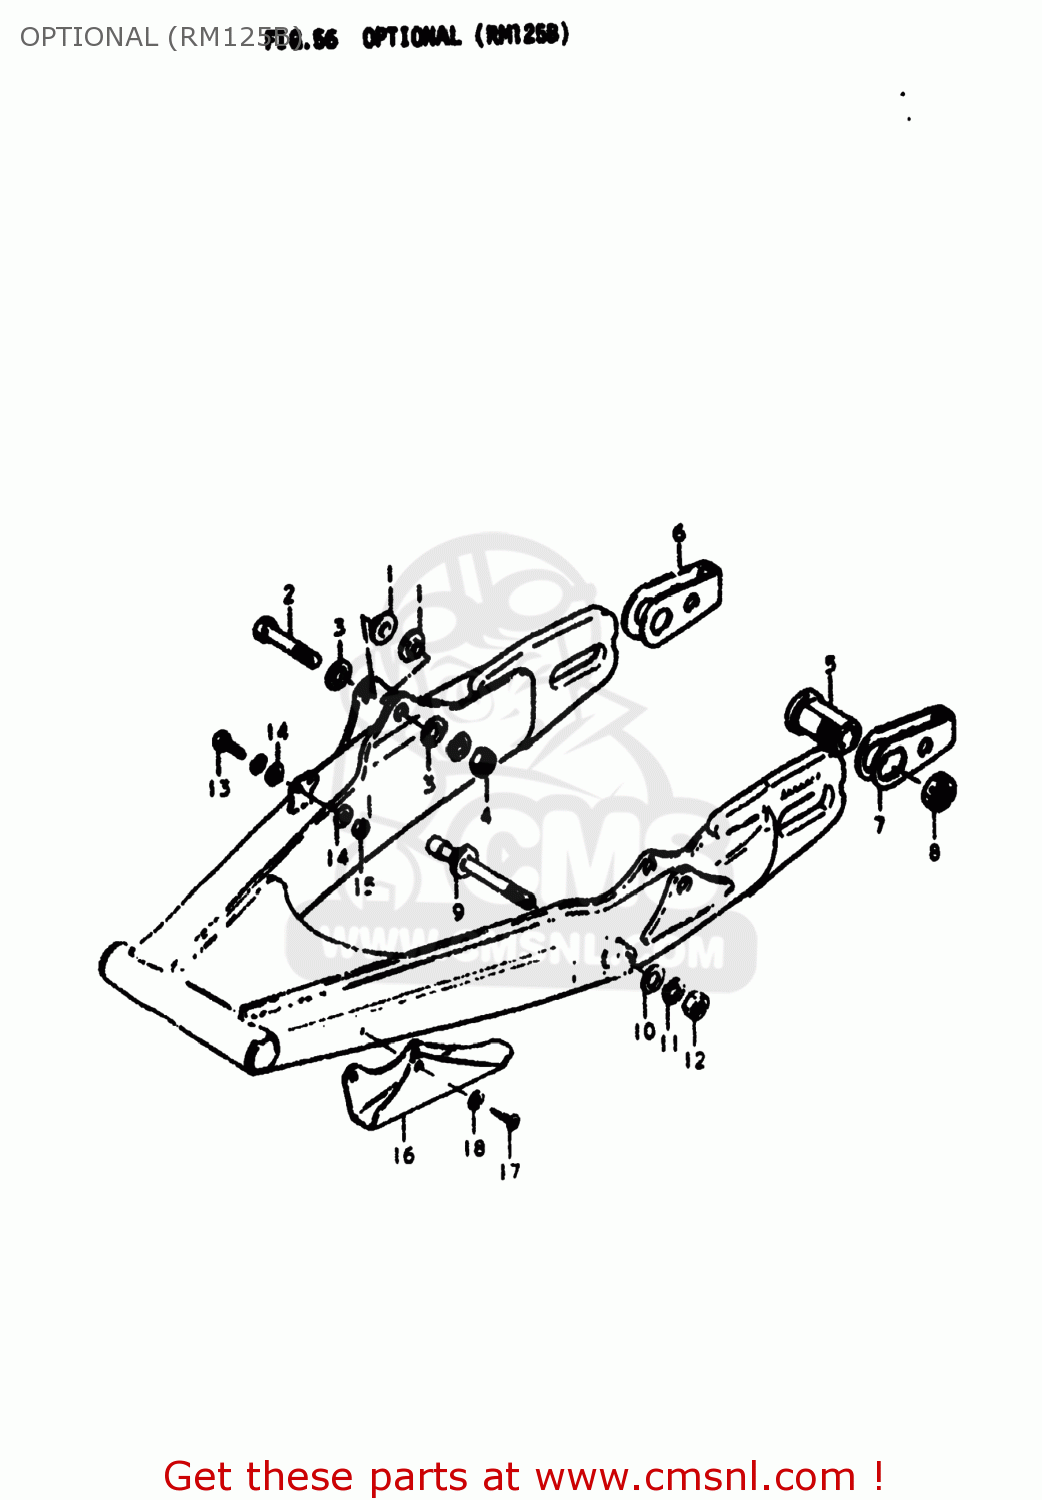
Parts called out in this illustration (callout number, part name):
1	WASHER
2	BOLT(10X48)
3	WASHER
4	NUT
5	SPACER,CHAIN ADJUSTER
6	ADJUSTER,CHAIN
7	ADJUSTER,CHAIN
8	NUT, REAR AXLE
9	HOLDER,CABLE TENSIONER
10	WASHER
11	LOCK WASHER
12	NUT
13	BOLT
14	WASHER
15	NUT
16	BUFFER,CHAIN TOUCH DEFLECTOR
17	SCREW
18	WASHER
